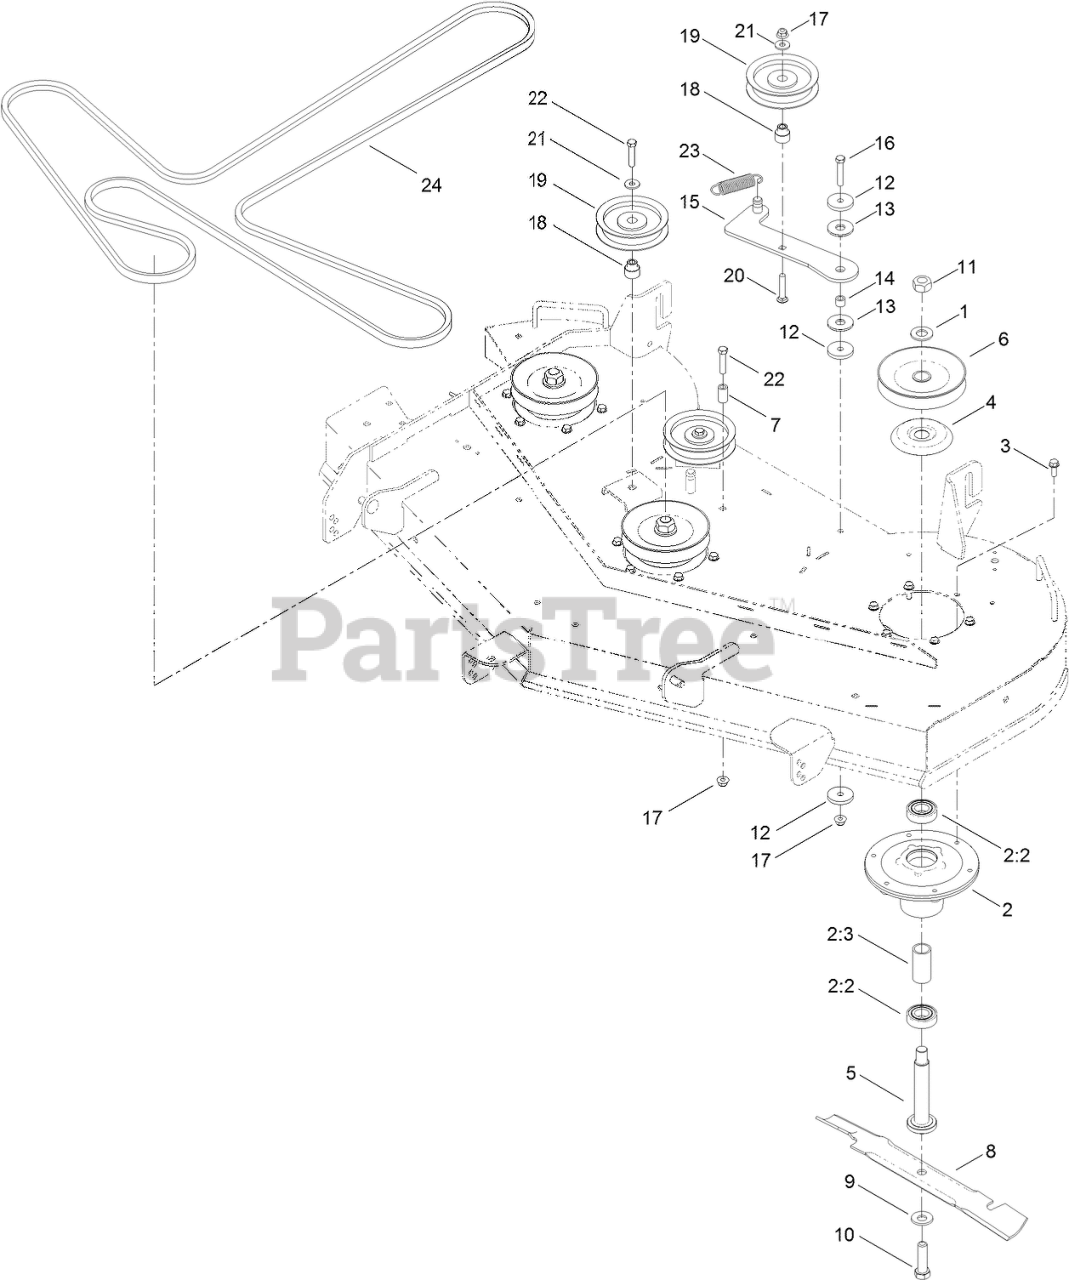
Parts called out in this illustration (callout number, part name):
1	WASHER
2	SPINDLE ASM
2:2	BEARING-BALL
2:3	SPACER-BEARING
3	SCREW-TAPTITE
4	SHIELD-BEARING
5	SHAFT-SPINDLE
6	PULLEY
7	SPACER
8	BLADE-HI FLO
9	WASHER-BELLEVILLE
10	SCREW-BLADE
11	NUT-HEX
12	WASHER-PLAIN
13	WASHER-FRICTION, COMPOSITE
14	BUSHING-LEVER, LIFT
15	ARM-IDLER
16	SCREW-HH
17	NUT-HF, NI
18	BUSHING-IDLER
19	PULLEY-IDLER
20	SCREW-CARR
21	WASHER-HARDENED
22	SCREW-HH
23	SPRING-EXTENSION
24	V-BELT
